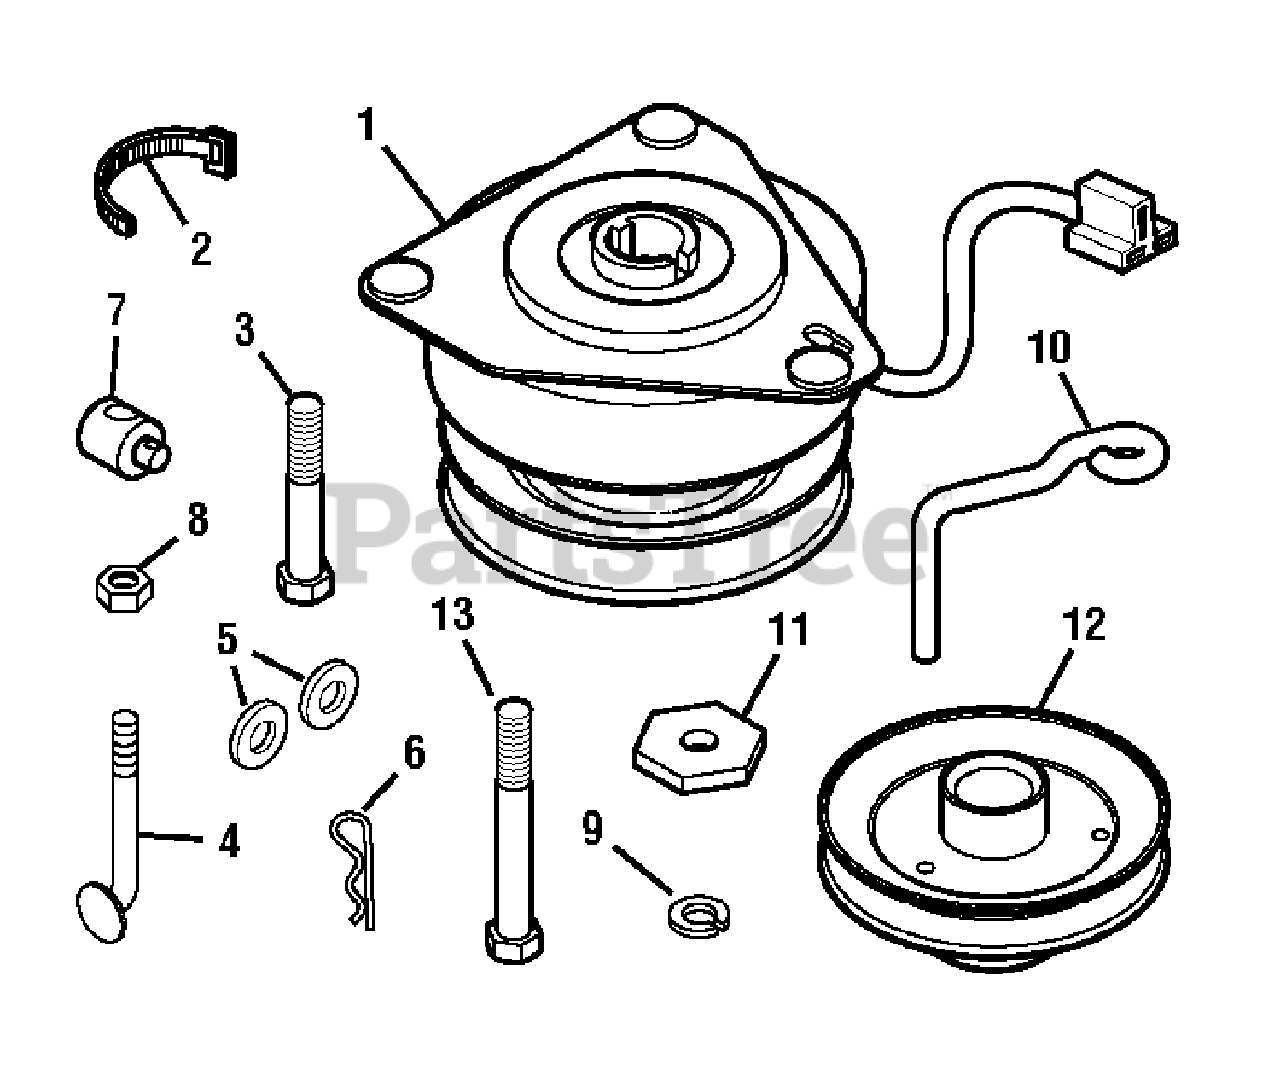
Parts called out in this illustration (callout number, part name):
1	CLUTCH, Electric
2	TIE, Self Locking, 3-5/8
3	SCREW, Taptite, 3/8-16 x 1-1/2
4	J-HOOK, 5/16 x 2-5/8
5	WASHER, 3/8 Flat
6	HAIR PIN, 1.625"
7	TRUNNION
8	NUT, Hex, Jam, 5/16-18
9	LOCKWASHER 7/16
10	ROD, CLUTCH
11	WASHER, Hex 7/16" ID
12	PULLEY ASSY
13	CAPSCREW, Hex, 7/16-20 x 3-1/2
